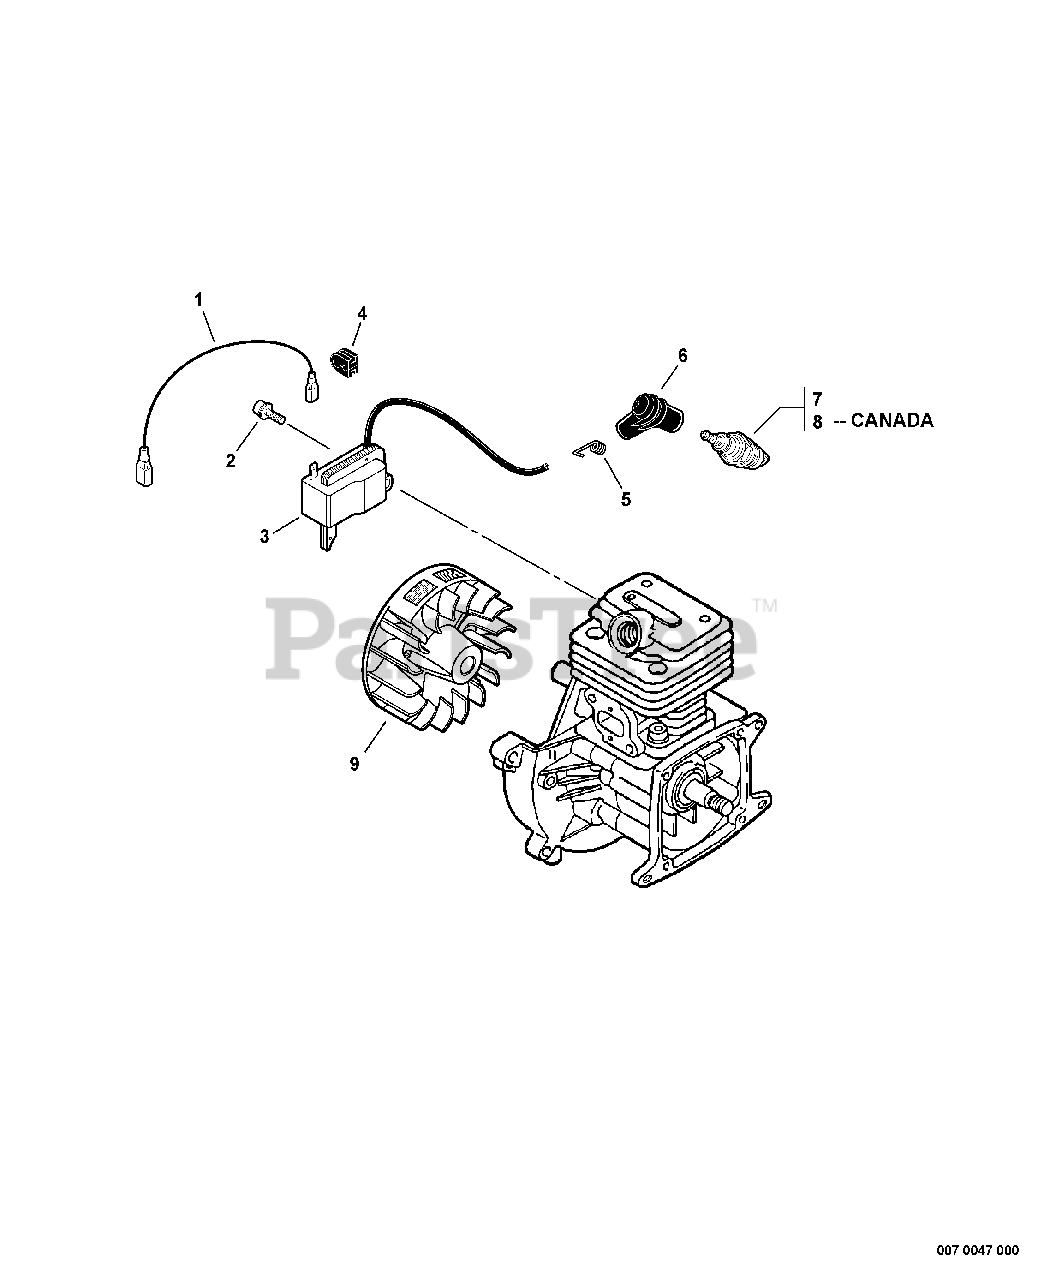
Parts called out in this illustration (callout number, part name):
1	LEAD - IGNITION
2	BOLT 5×16
3	COIL, IGNITION
5	TERMINAL, SPARK PLUG
6	CAP, SPARK PLUG
7	SPARK PLUG - BPM-7Y
8	SPARK PLUG - BPMR7A
9	FLYWHEEL
